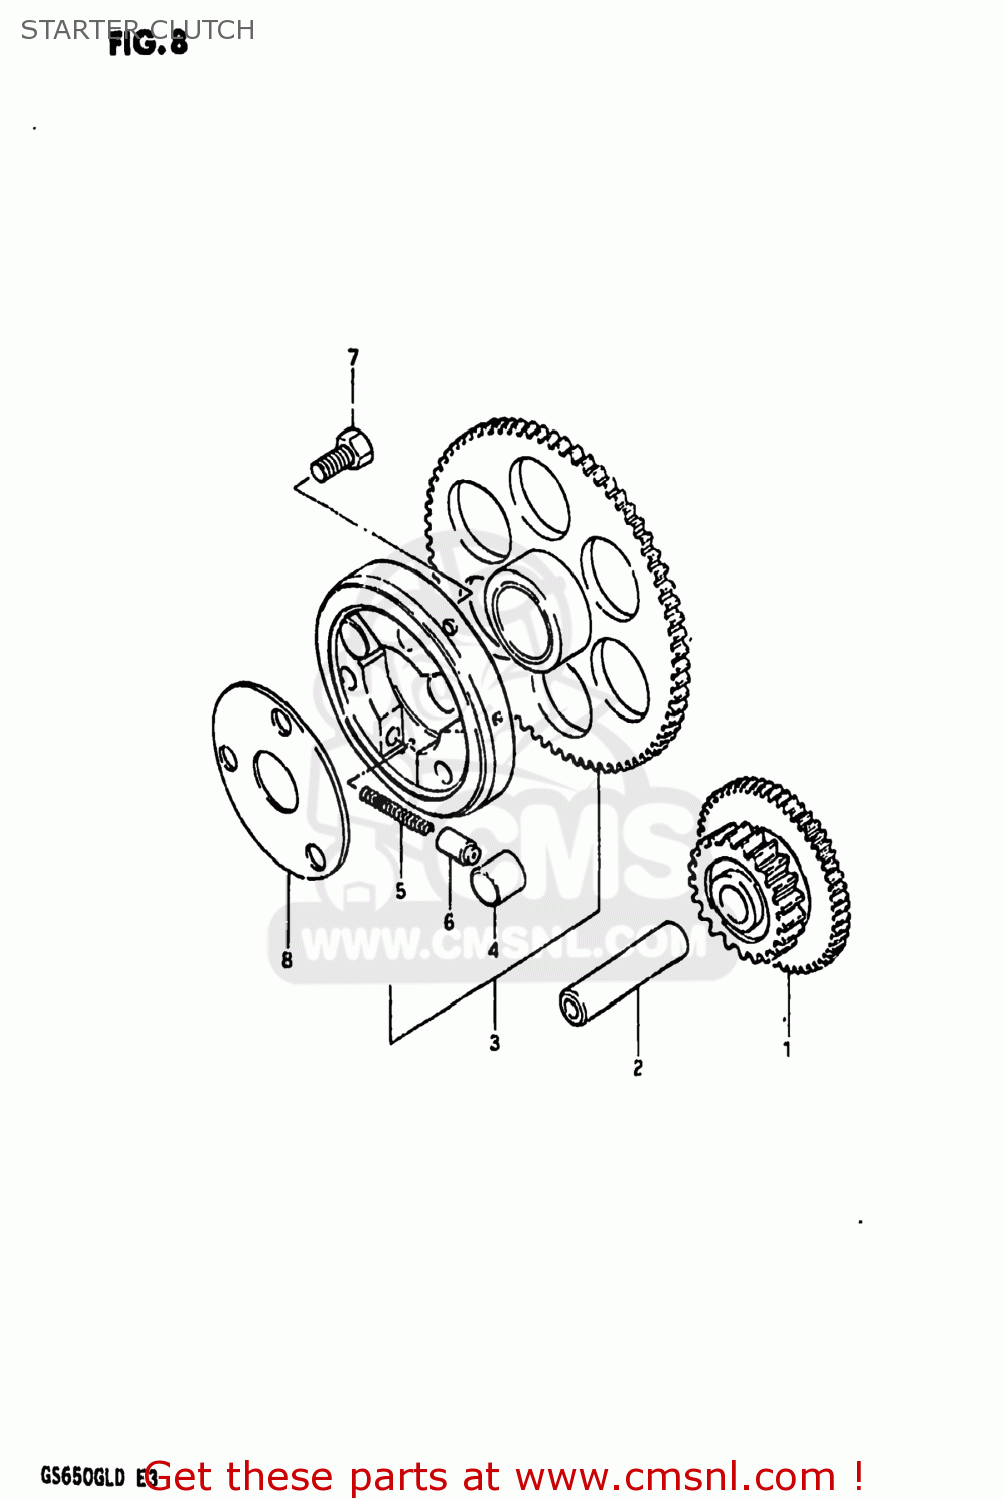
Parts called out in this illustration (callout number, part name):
1	GEAR,STARTER IDLE
2	PIN(7.4X13X56)
3	CLUTCH SET,STARTER
4	ROLLER(15X13)
5	SPRING
6	PIECE,PUSH
7	BOLT
8	SHIM,STARTER CLUTCH HUB
